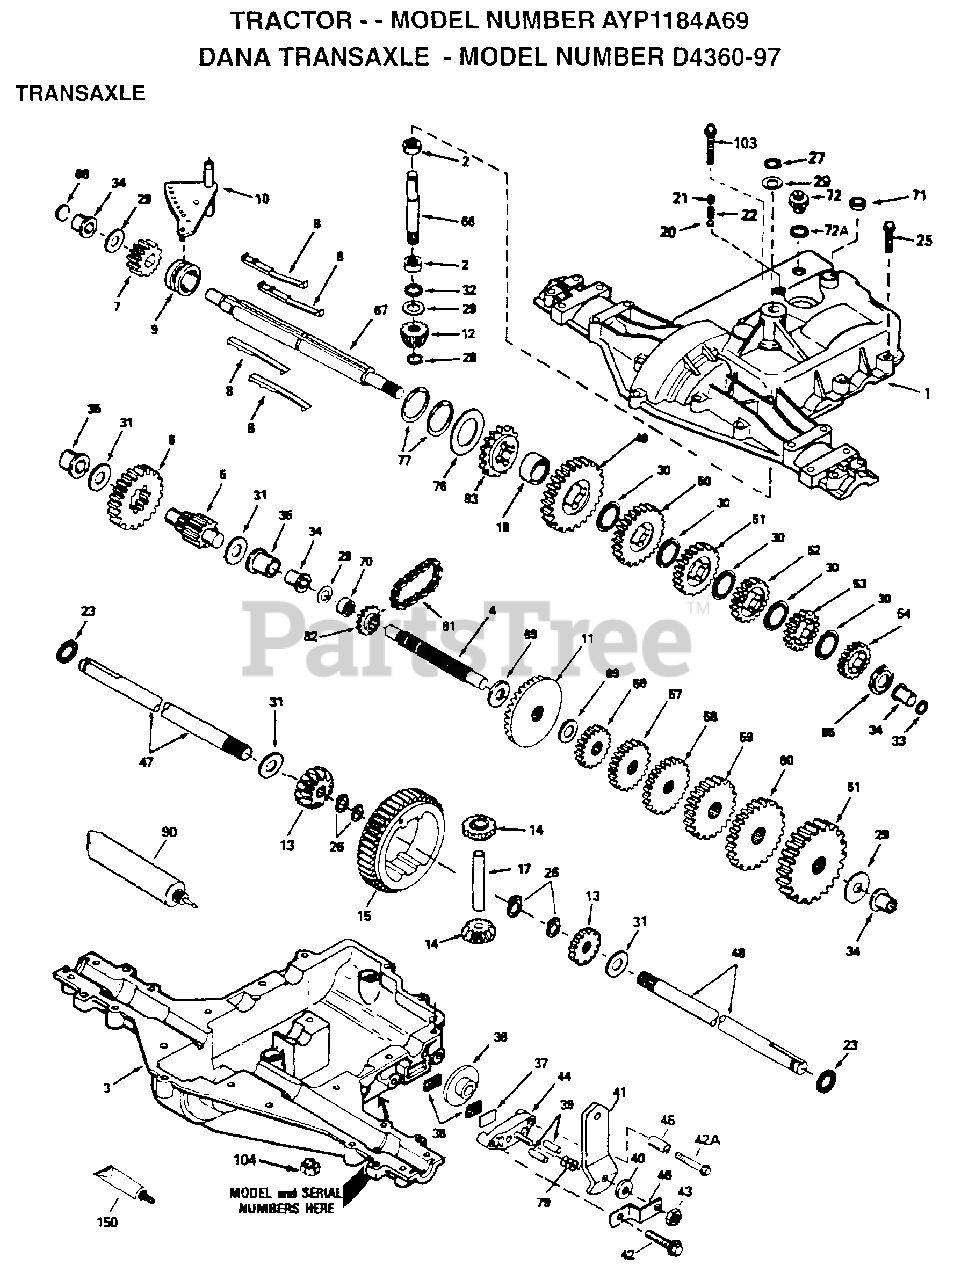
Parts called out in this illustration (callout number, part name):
1	HARNESS.IGNITION
4	"SPRING, DETENT LT"
5	"SCREW, SET LT"
6	SHIFTER.ASM.KIT.
7	SHIFTER BOOT
8	PUCK T
10	RETAINING RING LT
11	ASM KIT SHIM 4689
12	PLUG.PLASTIC
13	WASHER T
14	KEY WOODRUFF-DANA
17	"RING,RETAINING LT"
18	"CHAIN,24 PTCH LT"
19	BEARING.FLNG.5510
20	GEAR SPUR 14 TTH
21	COLLAR CLUTCH
22	KIT.ASM.CLTCH KEY
23	BEARING.FLNG.5511
24	SHAFT INTER 5404
25	WOODRUFF KEY
26	"RING,RETAINING LT"
27	SPROCKET 18T T
28	SPACER YT
29	GEAR SPUR 37 TTH
30	GEAR SPUR 35 TTH
31	GEAR SPUR 30T
32	GEAR 25T LT
33	GEAR SPUR 22 TT
34	SPUR GEAR 19T
35	"WASHER, PLAIN LT"
36	WASHER 025
37	SPACER
38	ASSM GEAR COMB
39	SHAFT IDLER
40	SPACER T
41	SPROCKET 9T LT
43	ASM KIT SHIM
44	SHAFT T
45	"SCREW, TAPPING LT"
46	GEAR SPUR 12 TTH
48	"GEAR, SPUR 25T LT"
49	GEAR 28T T
50	"GEAR, SPUR 31T LT"
51	WASHER 060
52	NEOPRENE WASHER
53	WASHER 031
55	GEAR 15T T
56	"RING,RETAINING LT"
58	SHAFT T
59	"GEAR,MITER 15T YT"
61	HOUSING LOWER TNS
62	PUCK T
63	BRAKE DISC. T
64	SPACER LT
66	PIN T
69	WASHER LT
71	NUT.LOCK.5/16-24
72	SEAL.OIL.DAN.5508
